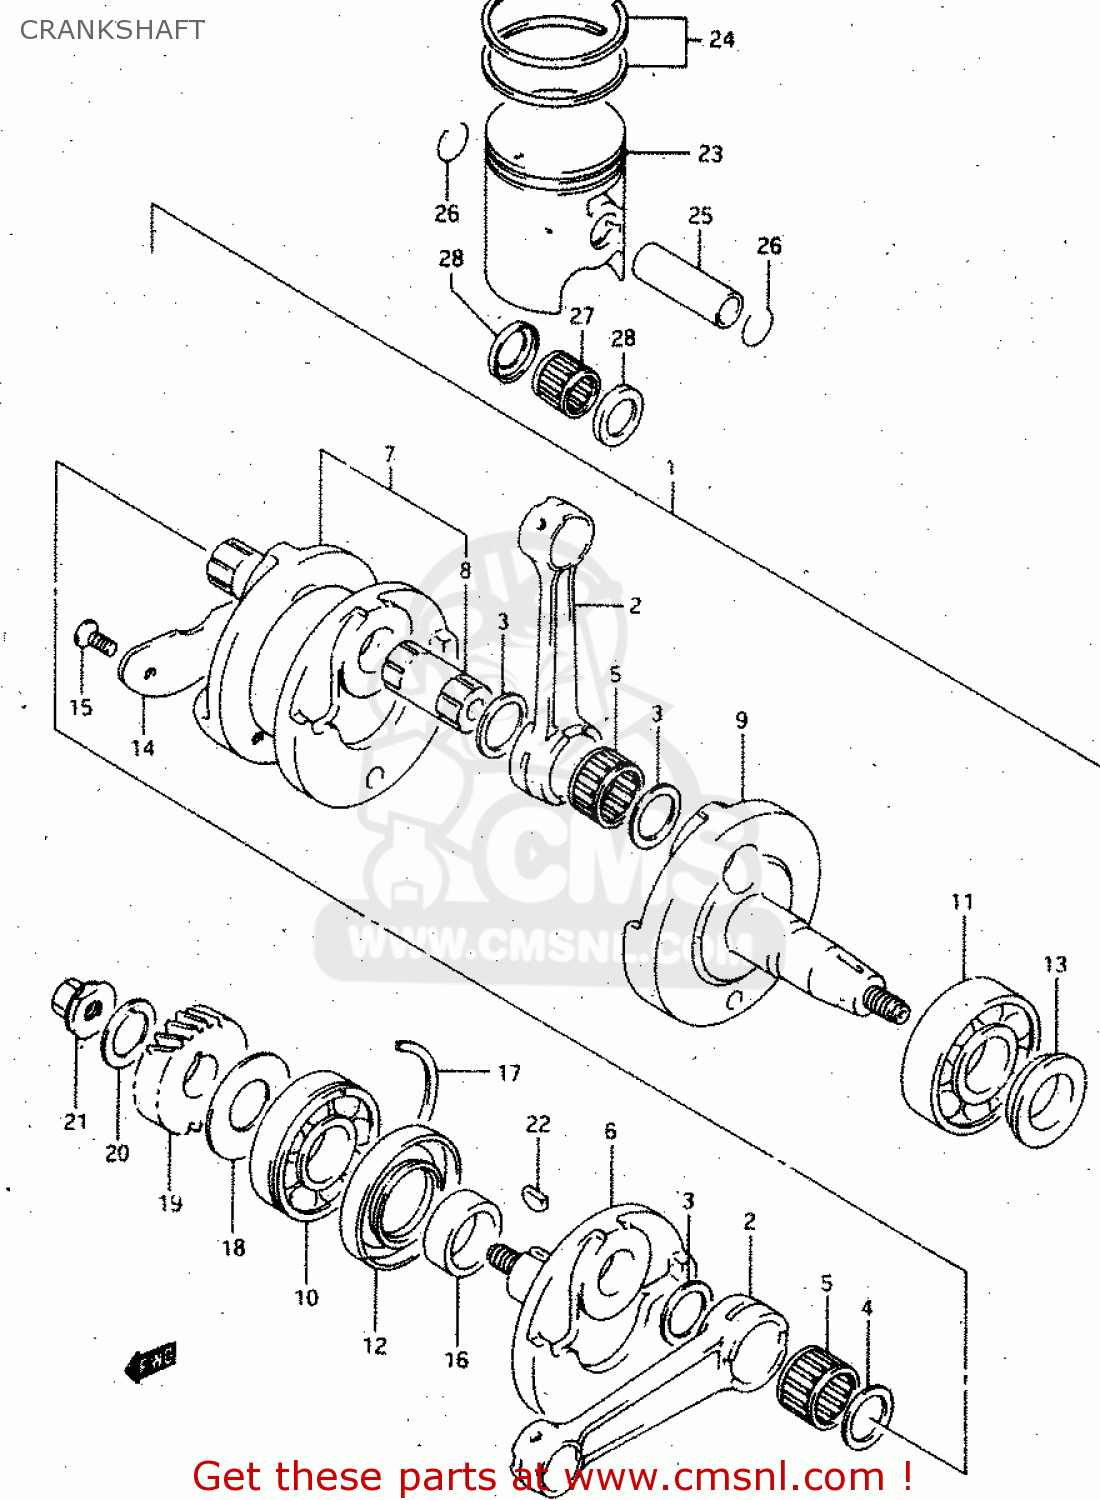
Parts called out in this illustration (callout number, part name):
1	CRANKSHAFT ASSY
2	ROD,CONNECTING
3	WASHER(22X27.5X1.5)
4	WASHER(22X27.5X2)
5	ROLLER BEARING (22X28X1
6	CRANKSHAFT,R
7	CRANKSHAFT,MIDDLE
8	PIN,CRANK
9	CRANKSHAFT,L
10	BEARING(25X62X17)
11	BEARING(25X62X17)
12	SEAL,OIL(32X62X6X7.5)
13	SEAL,OIL(25X36X6)
14	BALANCER,CRANKSHAFT
15	SCREW
16	SPACER(25.2X32X9)
17	C RING
18	SHIM(20X48X0.5)
19	GEAR,PRIMARY DRIVE
20	WASHER
21	NUT
22	KEY
23	PISTON
24	RING SET,PISTON
25	PIN,PISTON
26	RING,SNAP 16MM
27	BEARING(16X20X17.8)
28	WASHER
